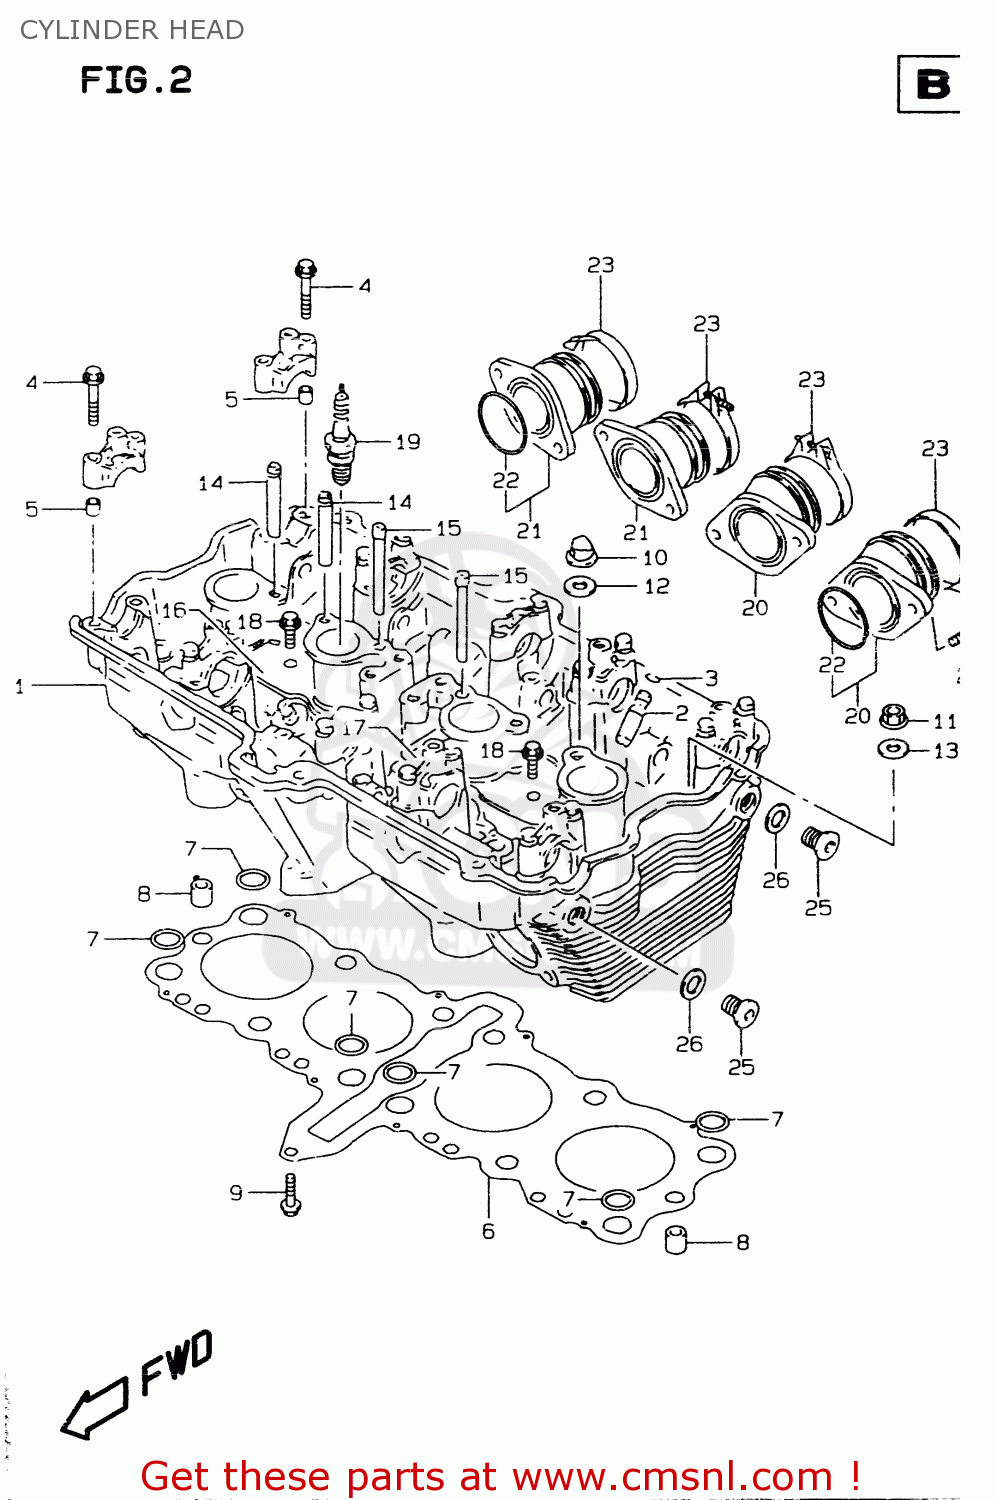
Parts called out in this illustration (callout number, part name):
1	HEAD ASSY,CYLINDER
2	GUIDE,VALVE
3	RING,SNAP
4	BOLT(6X39)
5	PIN(6.2X8X11)
6	GASKET,CYLINDER HEAD (NAS)
7	O RING(D:2.6,ID:12.1)
8	PIN
9	BOLT
10	NUT
11	NUT
12	GASKET(10.2X20X2).3 (NAS)
13	WASHER (10.5X22X2.3)
14	PIPE,OIL NO.1
15	PIPE,OIL NO.3
16	PLATE,OIL PIPE,R
17	PLATE,OIL PIPE,L
18	BOLT
19	PLUG,SPARK(CR9EK)
20	PIPE ASSY,INTAKE,L
21	PIPE ASSY,INTAKE,R
22	O RING(D:2.4,ID:39.7)
23	CLAMP
24	BOLT MAGNETO S
25	PLUG
26	GASKET(13.8X18.8X4.8) (NAS)
